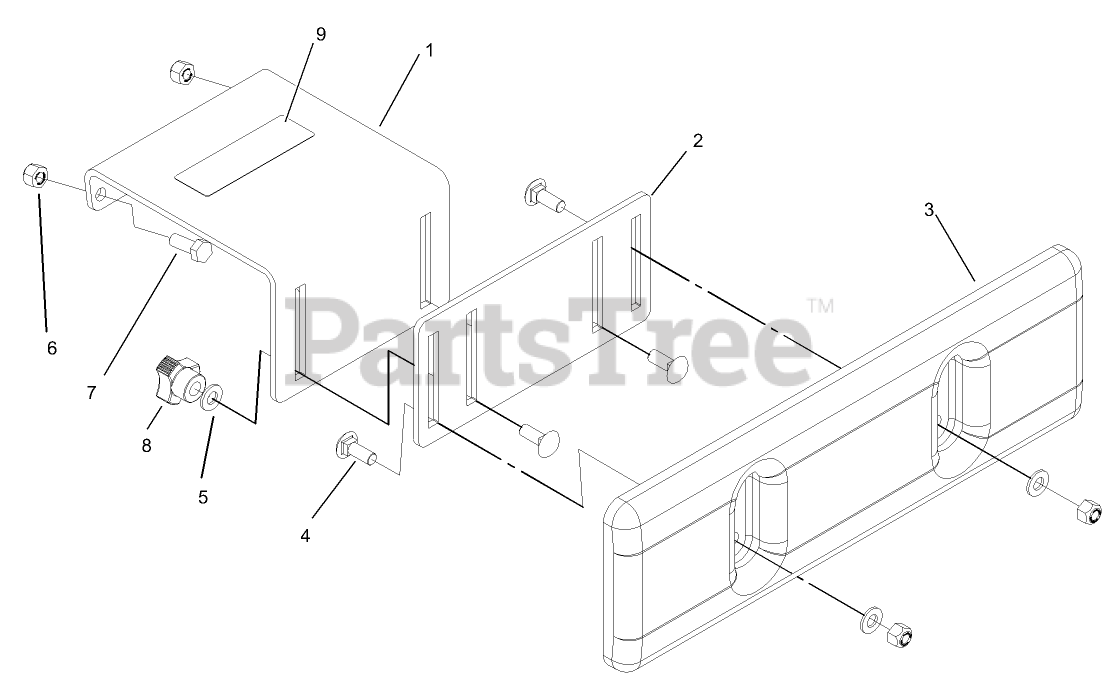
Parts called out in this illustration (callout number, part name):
1	Thigh Support ASM
2	PLATE-ADJUSTING
3	SUPPORT-THIGH
4	SCREW-CARR
5	WASHER-FLAT
6	NUT-LOCK, NI
7	SCREW-HH
8	Knob-Adjustment
9	DECAL-MANUAL
9	Decal-Information, Ce
